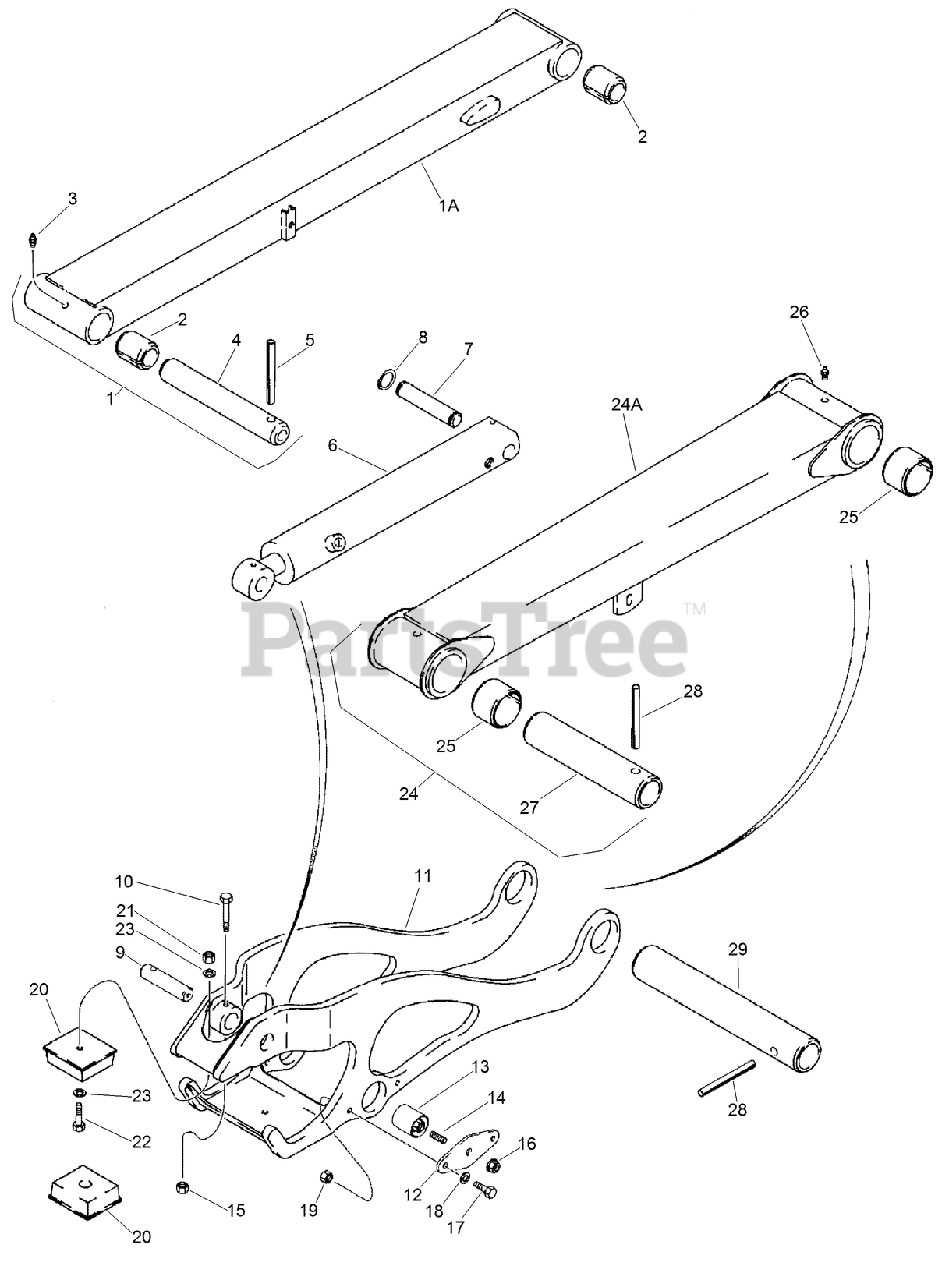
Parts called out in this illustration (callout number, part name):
1	ARM ASM-plow lift, upper
1A	ARM-plow lift, upper
2	BUSHING-plow lift arm
3	FITTING-Lube 1/4-28 Tpr SAE-LT .54 Long
4	PIN-PLOW ARM, UPPER
5	PIN-SPIRAL
6	CYLINDER-PLOW LIFT
7	PIN-PLOW
8	RING-RETAINING
9	PIN-ROD
10	BOLT-hex, 3/8 NC x 3 inch
11	CRADLE-plow lift
12	PLATE-bumper mounting
13	MOUNT-ISOLATOR
15	NUT-HEX
16	NUT-hex serrated flange, 1/2 inch NC
17	BOLT-hex, 3/8 NC x 1-1/2 inch
18	WASHER-FLAT
19	NUT-HEX
20	BUMPER
21	NUT-HEX
22	BOLT
23	WASHER-FLAT
24	ARM ASM-plow lift, lower
24A	ARM-plow lift, lower
25	BUSHING
26	FITTING-Lube 1/4-28 Tpr SAE-LT .54 Long
27	PIN-PLOW ARM, LOWER REAR
28	PIN-SPIRAL
29	PIN-lower plow lift arm, front
